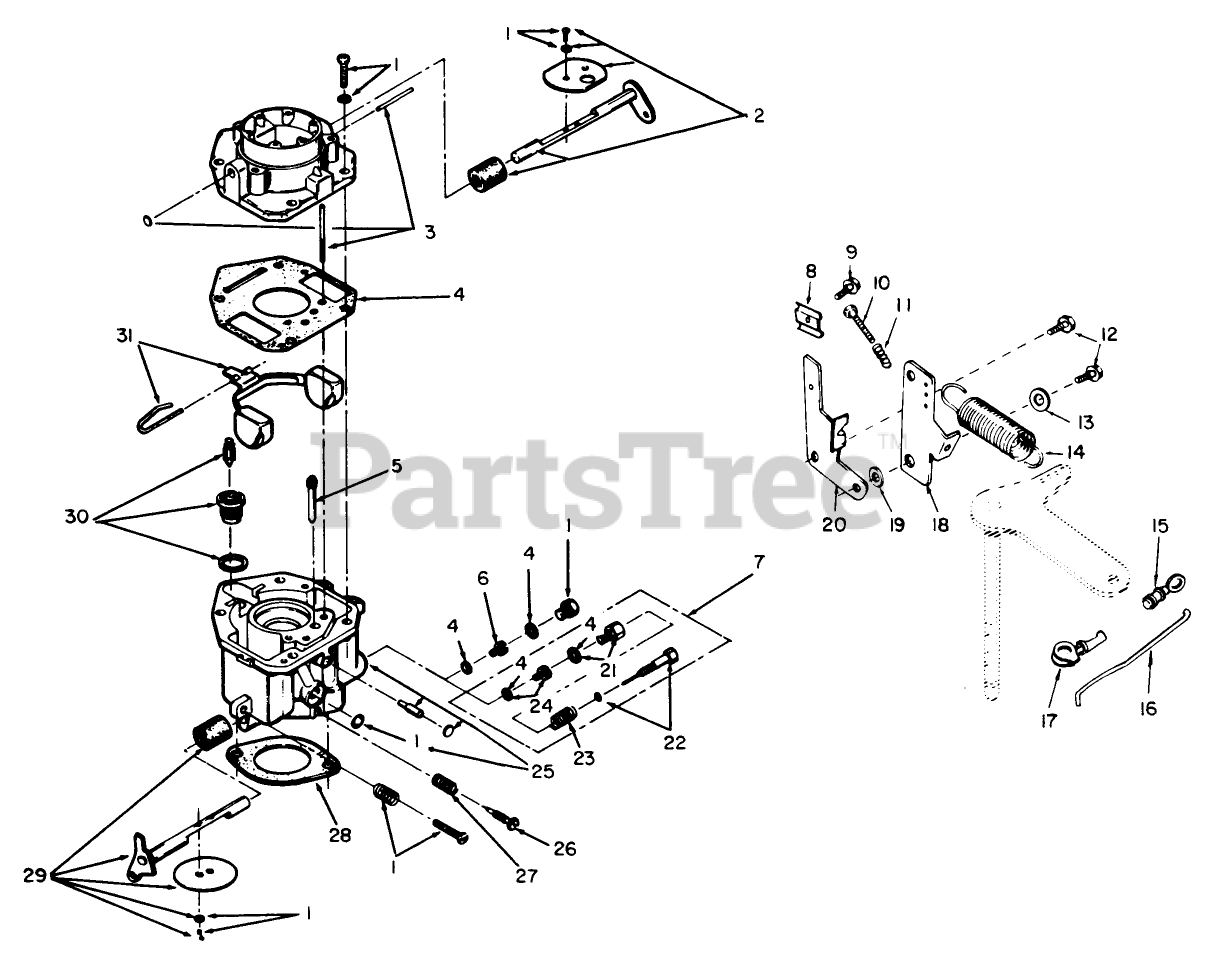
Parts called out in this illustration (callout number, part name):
3	Intake, Air
10	SCREW-TAP
11	SPRING
12	SCREW-HWH
19	BUSHING
20	BRACKET-GOVERNOR
30	FLOAT VALVE
31	FLOAT
